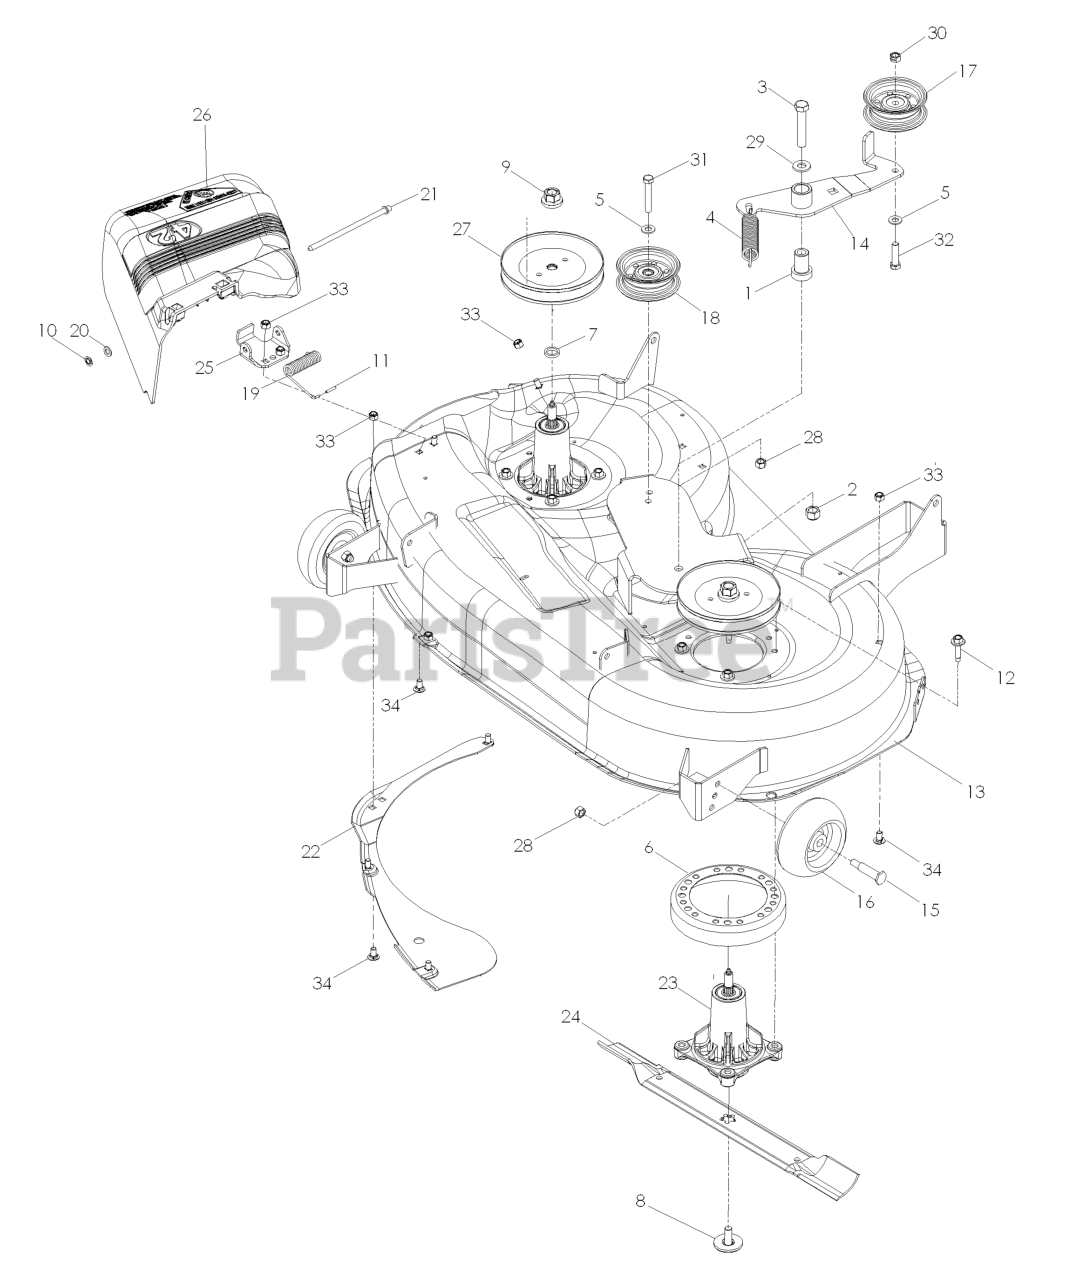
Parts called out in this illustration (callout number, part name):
1	IDLER SPINDLE
2	NUT 1/2-13 HEX NYLOC ZD
3	HCS 1/2C X 2 3/4
5	WASHER 3/8 SAE FLAT
6	STRIPPER-ROUND-UNIVERSAL
7	WASHER-SPACER
8	BOLT.WASHER.ASM.7/16-2
9	LOCKNUT - 9/16
10	PUSH NUT
11	CAP-SLEEVE
12	WASHER HEAD SCREW
13	DECK W/DECALS 42" ORANGE
14	DECK IDLER ARM WELDMENT
15	BOLT, SHOULDER
16	WHEEL GUAGE
17	PULLEY, IDLER, SHORT
18	IDLER PULLEY ASM
19	SPRING, TORSION DEFLECTOR
20	WASHER, 11/32 X 5/8 X 16 GA
21	ROD, HINGE
22	BAFFLE VORTEX 42
23	MANDREL GREASABLE
24	BLADE 42" MULCHING STD
25	BRKT.DEFLECTOR.38"2005+
26	DEFLECTOR 42
27	PULLEY.MANDREL.5.438.P
28	NUT 3/8-16 NYLOC
29	WASHER 1/2" FLAT
30	NUT 3/8C CENTERBLOCK
31	HCS 3/8C X 2 1/4
32	HCS 3/8C X 1 1/2
33	NUT 5/16 NYLOC
34	CARRIAGE BOLT 5/16C X 5/8"
